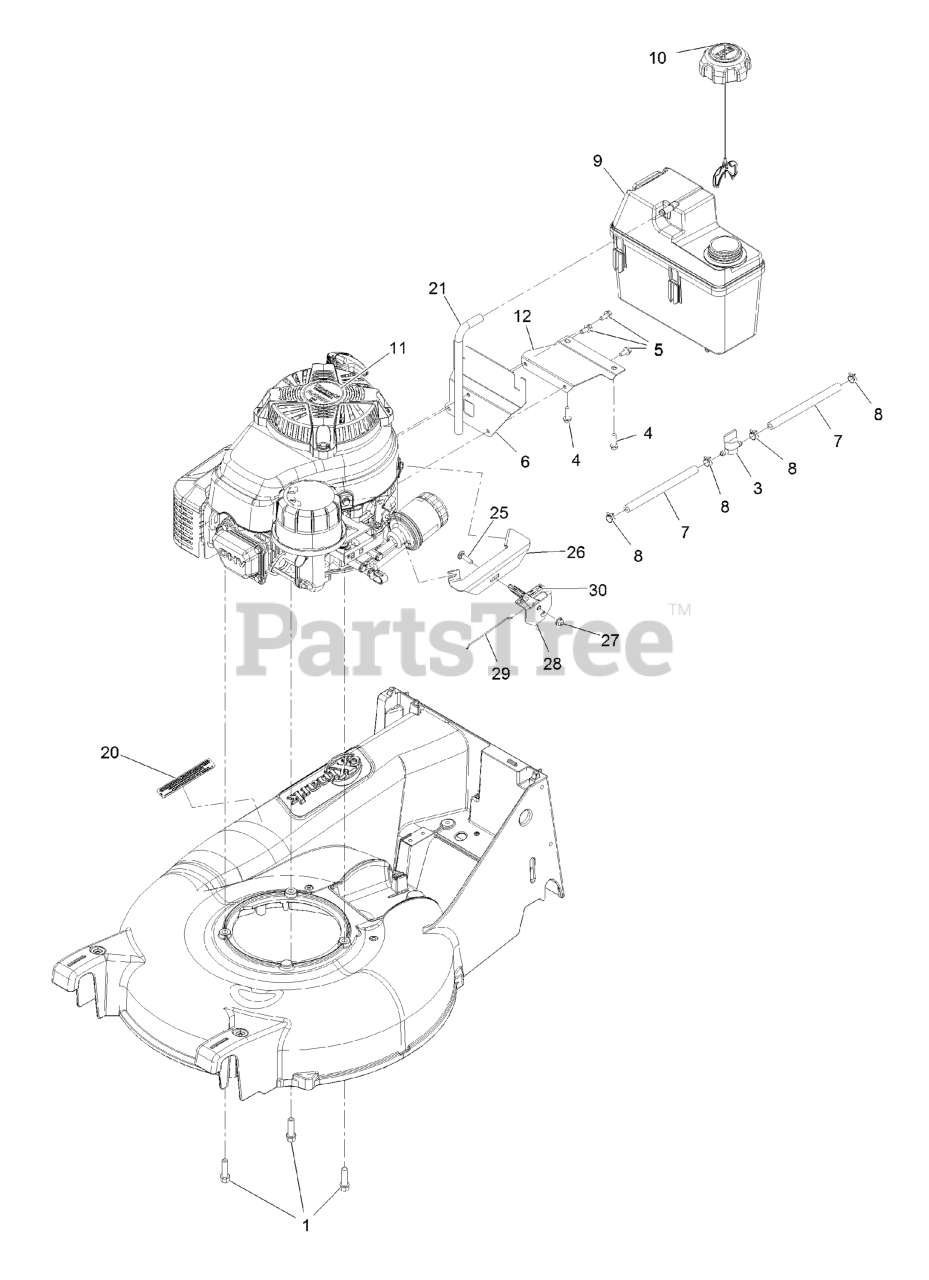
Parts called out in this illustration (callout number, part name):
1	SCREW-TAPTITE
3	VALVE-FUEL
4	SCREW-HWH
5	SCREW-HWH
6	BRACKET-TANK, MOUNTING
7	HOSE-FUEL
8	CLAMP-HOSE
9	TANK-FUEL
10	CAP-FUEL
12	BRACKET-TANK, SUPPORT
20	DECAL-ARRESTOR, SPARK
21	HOSE-VENT, CANISTER
25	SCREW-CARR
26	BRACKET-MOUNT, THROTTLE
28	CONTROL-THROTTLE
29	WIRE-CONTROL
30	DECAL-THROTTLE, CHOKE
